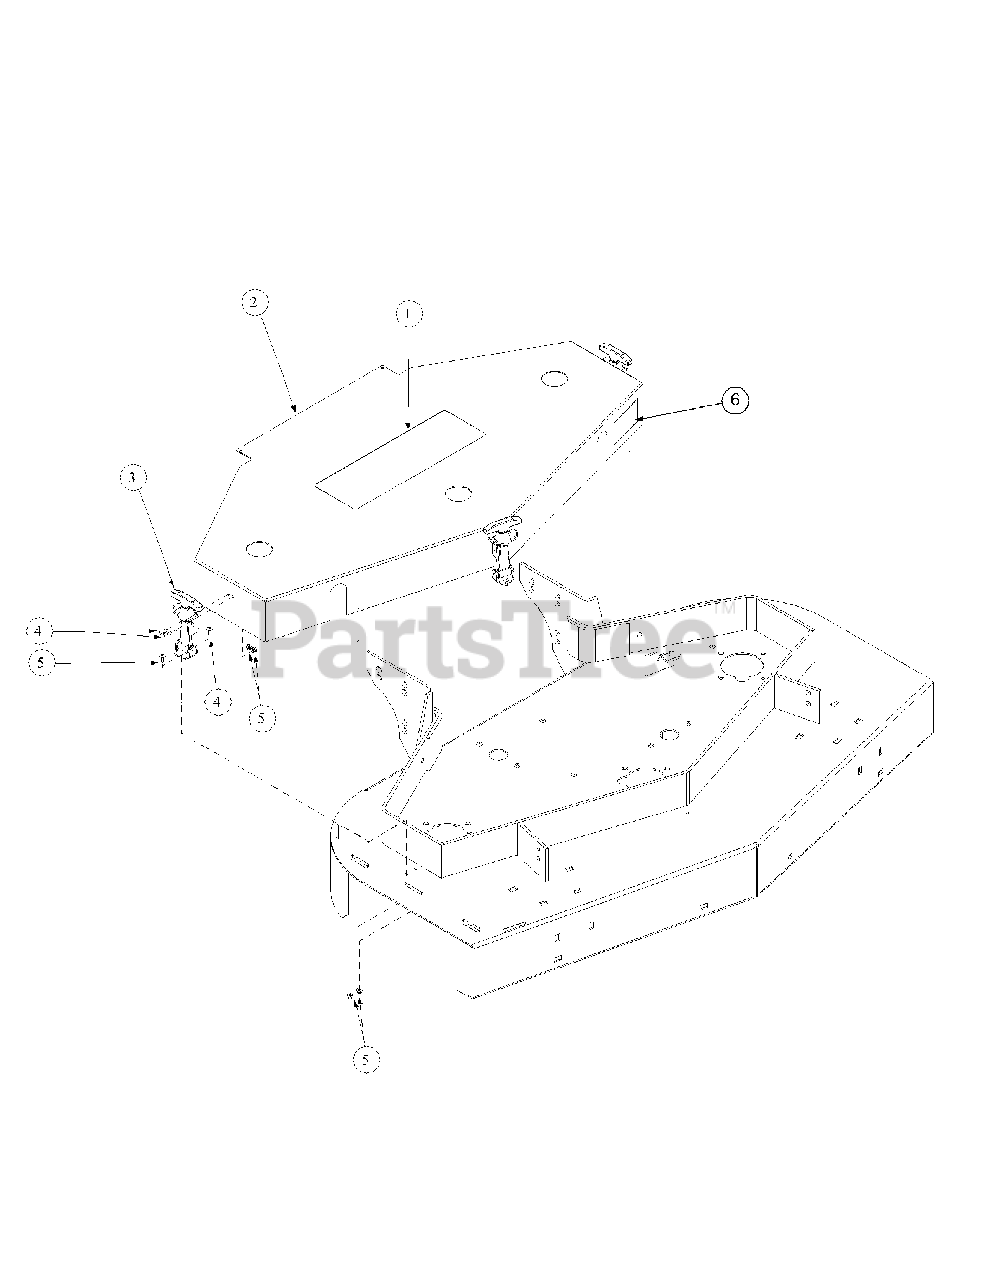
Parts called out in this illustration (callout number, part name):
1	Label Commercial Mower
2	Deck Cover 48"
3	Rubber Latch Hood
4	Machine Screw, 10-24 x 1/2
5	Lock Nut, Nylon Insert, #10-24
6	Label, H1748
